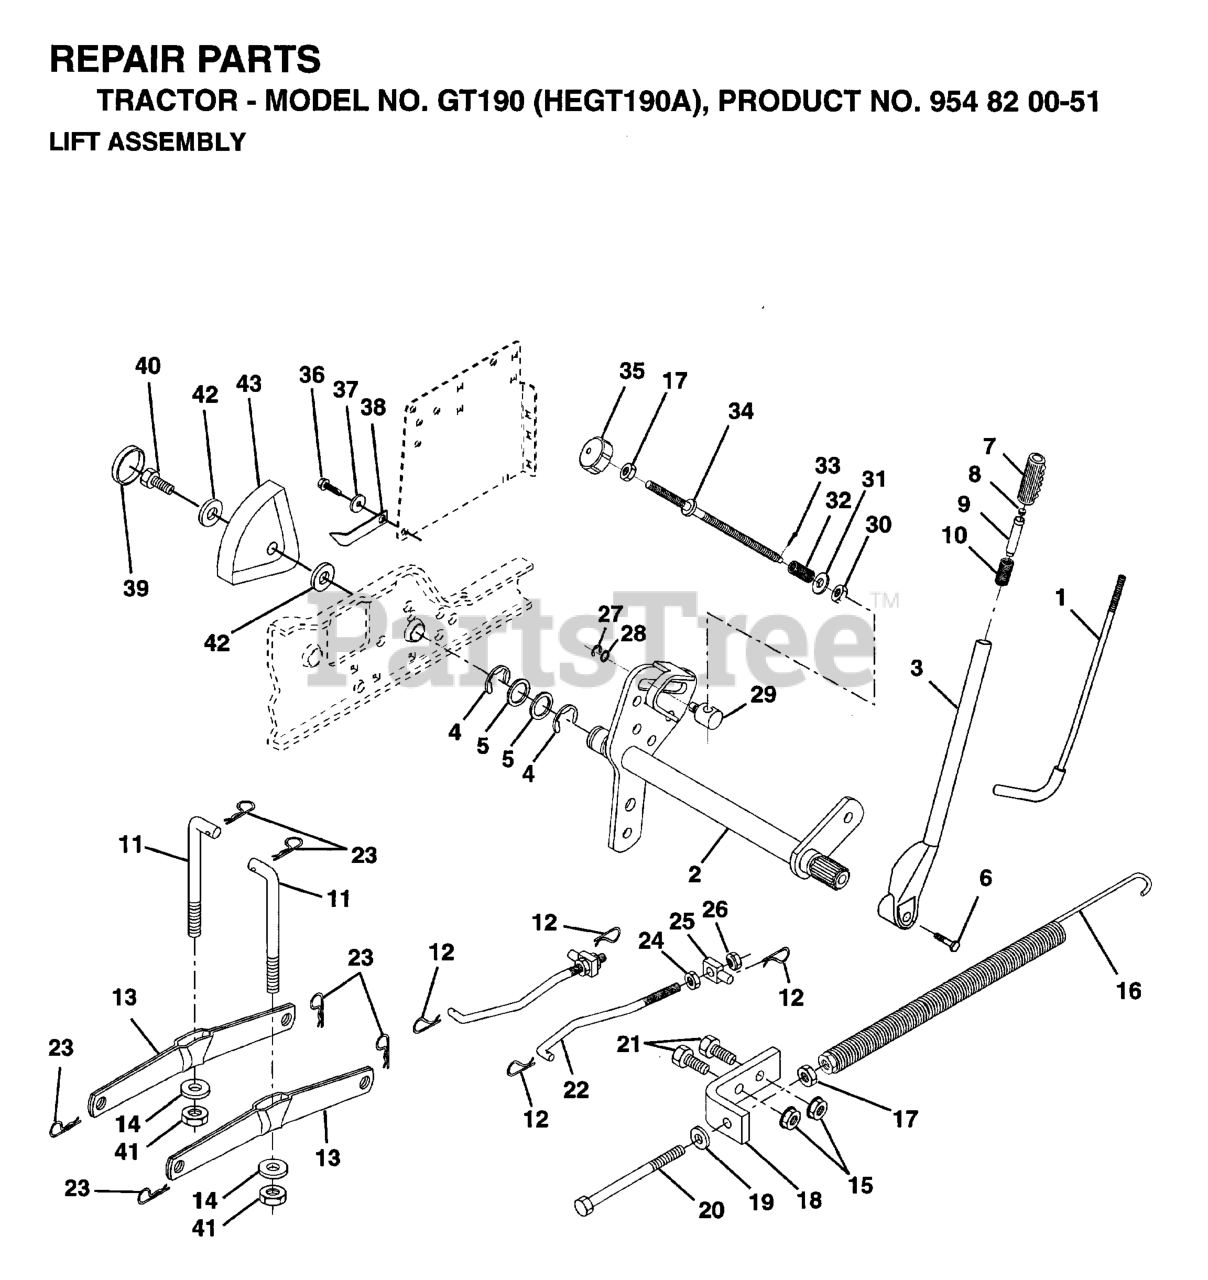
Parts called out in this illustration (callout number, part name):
1	LEVER ROD LT
2	SHAFT ASM, LIFT VGT
3	LIFT LEVER KIT
5	Washer 29/32 x 1 - 1/4 x 16 Ga.
6	BOLT
7	GRIP HANDLE
8	PLUNGER BUT KIT
9	PLUNGER BUT KIT
10	SPRING**
11	LINK LIFT
12	SPRING RETAINER
13	ARM.REAR.SUSPENSION
14	BEARING PIVOT
16	LIFT SPRING
17	NUT
19	WASHER
21	BOLT
22	FRONT LINK
23	RETAINER-SPRNG RB
24	NUT.HEX.JAM.1/2-13
25	TRUNION
26	NUT.LK.W/WSH.1/2.
27	Ring, Klip #T5304-37
28	Washer 15/32 x 3/4 x 16 Gauge
29	TRUNION LT
32	SPRING.COMP.INF.H
33	COTTER PIN
34	ROD.LIFT.ADJUSTABLE
35	KNOB INF 3/8-16
36	SCREW
38	POINTER HGT
40	SCREW.THDROL.5/16-18X3/4.TTY
41	NUT CROWNLOCK 3/8-24
43	HEIGHT INDICATOR
